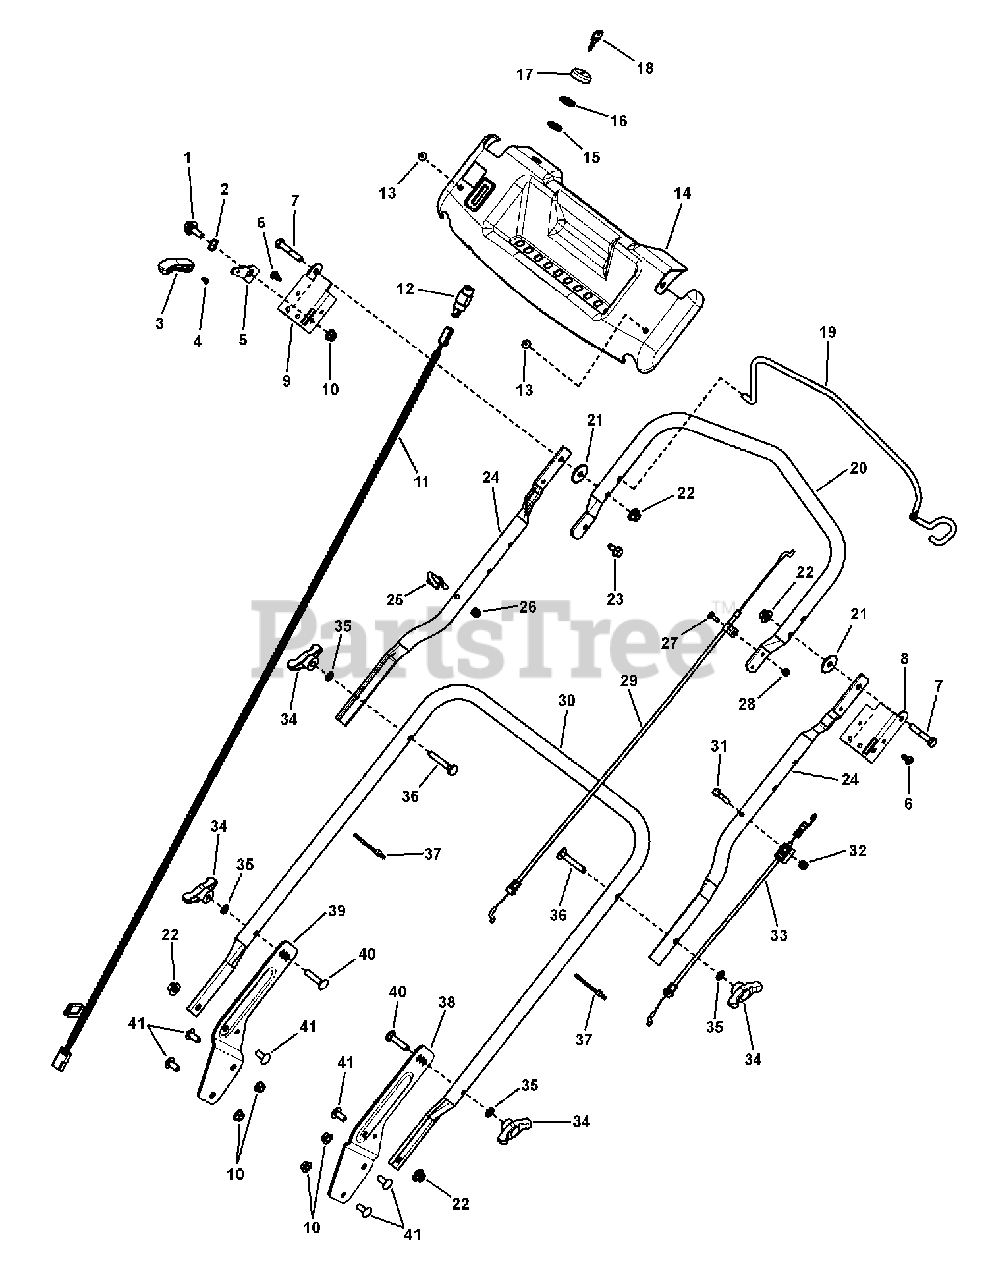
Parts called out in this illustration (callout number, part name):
1	BOLT, 5/16-18 Shoulder
2	WASHER, .531 x .781 Wave
3	LEVER, Lock Handle
4	RIVET, .157" Dia., Plastic Snap
5	HANDLE, Lock
6	SCREW, 1/4-20 x .55 Torx Self-Tap
7	SCREW, 5/16-18 x 1-3/4" Hex Head Cap, GR 5
8	BRACKET, Rotation Limit, LH
9	BRACKET, Rotation Limit, RH
10	NUT, 5/16-18, Serrated Lock Flange, GR5
11	WIRE HARNESS - Deere - JS35
12	SWITCH, Ignition (spring loaded ON/OFF 2 Prong)
13	Pop Rivet, .250 Dia.
14	PANEL, Upper Handle, 21 WBM, Black
14	PANEL, Upper Handle, 21 WBM Electric Start, Black
15	SPACER, .875 OD x .654 ID x .104
16	NUT, 5/8-32 Hex Lock
17	BEZEL, Black (Seal & Face Nut)
18	KEY, Ignition (set of 2)
19	BAIL, Pivot Handle
20	HANDLE, Pivot
21	WASHER, 5/16 Nylon
22	NUT, 5/16-18 Large Head Center Lock, Black
23	SCREW, 5/16-18 X .750, Washer Head Taptite
24	HANDLE, Upper, Pivot, 21"
25	ROPE GUIDE (1/4-20 thread)
26	NUT, 1/4-20 Hex Nyloc
27	BOLT, #10-24 x 1/2" Flat Head Square Neck
28	NUT, #10-24 Hex Nyloc
29	CABLE, OPC, Pivot Handle, 59.37"
30	HANDLE, Lower
31	SCREW, 1/4-20 x 1-3/4, Hex Head Cap, GR 5
32	NUT, 1/4-20 Hex Center Lock
33	CABLE, Drive, Adjustable 49.93"
34	KNOB, 5/16-18 Wing (Black)
35	WASHER, 5/16" Internal Tooth Lock
36	BOLT, 5/16-18 x 2" Curved Head Square Neck, GR 2
37	WIRE TIE,11 Inch Standard Black Nylon
38	BRACKET, Lower Handle, LH 21" WBM
39	BRACKET, Lower Handle RH 21" WBM
40	BOLT, 5/16-18 x 1-1/2" Round Head Square Neck
41	BOLT, 5/16-18 x 3/4" Round Head Short Square Neck, GR5 YZ
